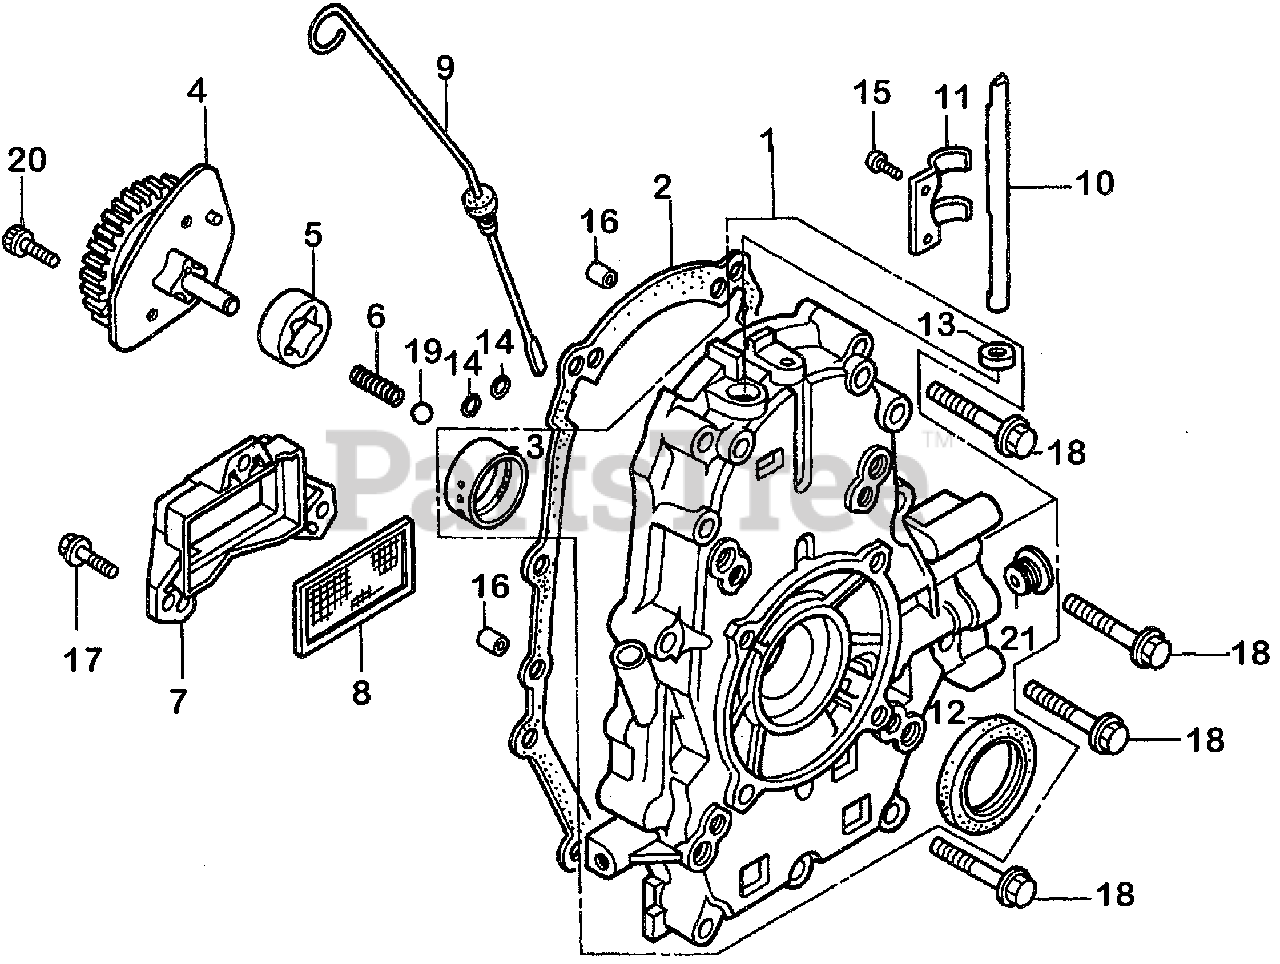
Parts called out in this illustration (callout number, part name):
1	COVER ASSY., CRANKCASE
2	GASKET, CASE COVER
3	BEARING A, MAIN (BLUE) (TO SELECT CORRECT BEARING, SEE THE SERVICE MANUAL.)
3	BEARING B, MAIN (BLACK) (TO SELECT CORRECT BEARING, SEE THE SERVICE MANUAL.)
3	BEARING C, MAIN (BROWN) (TO SELECT CORRECT BEARING, SEE THE SERVICE MANUAL.)
4	COVER ASSY., OIL PUMP (THREE BOLTS)
5	ROTOR, OIL PUMP (OUTER)
6	SPRING, RELIEF VALVE
7	COVER, OIL FILTER
8	SCREEN, OIL FILTER
9	DIPSTICK, OIL
10	SHAFT, GOVERNOR ARM (NOT AVAILABLE)
11	FORK, GOVERNOR
12	OIL SEAL (38X58X11)
13	OIL SEAL (10X16X4.5)
14	O-RING (13X3.0)
15	SCREW, PAN (5X10)
16	PIN A, DOWEL (8X14)
17	BOLT, FLANGE (6X20)
18	BOLT, FLANGE (8X50)
19	BALL, STEEL (#12) (3/8)
20	BOLT, SOCKET (6X16)
21	BOLT, SEALING
